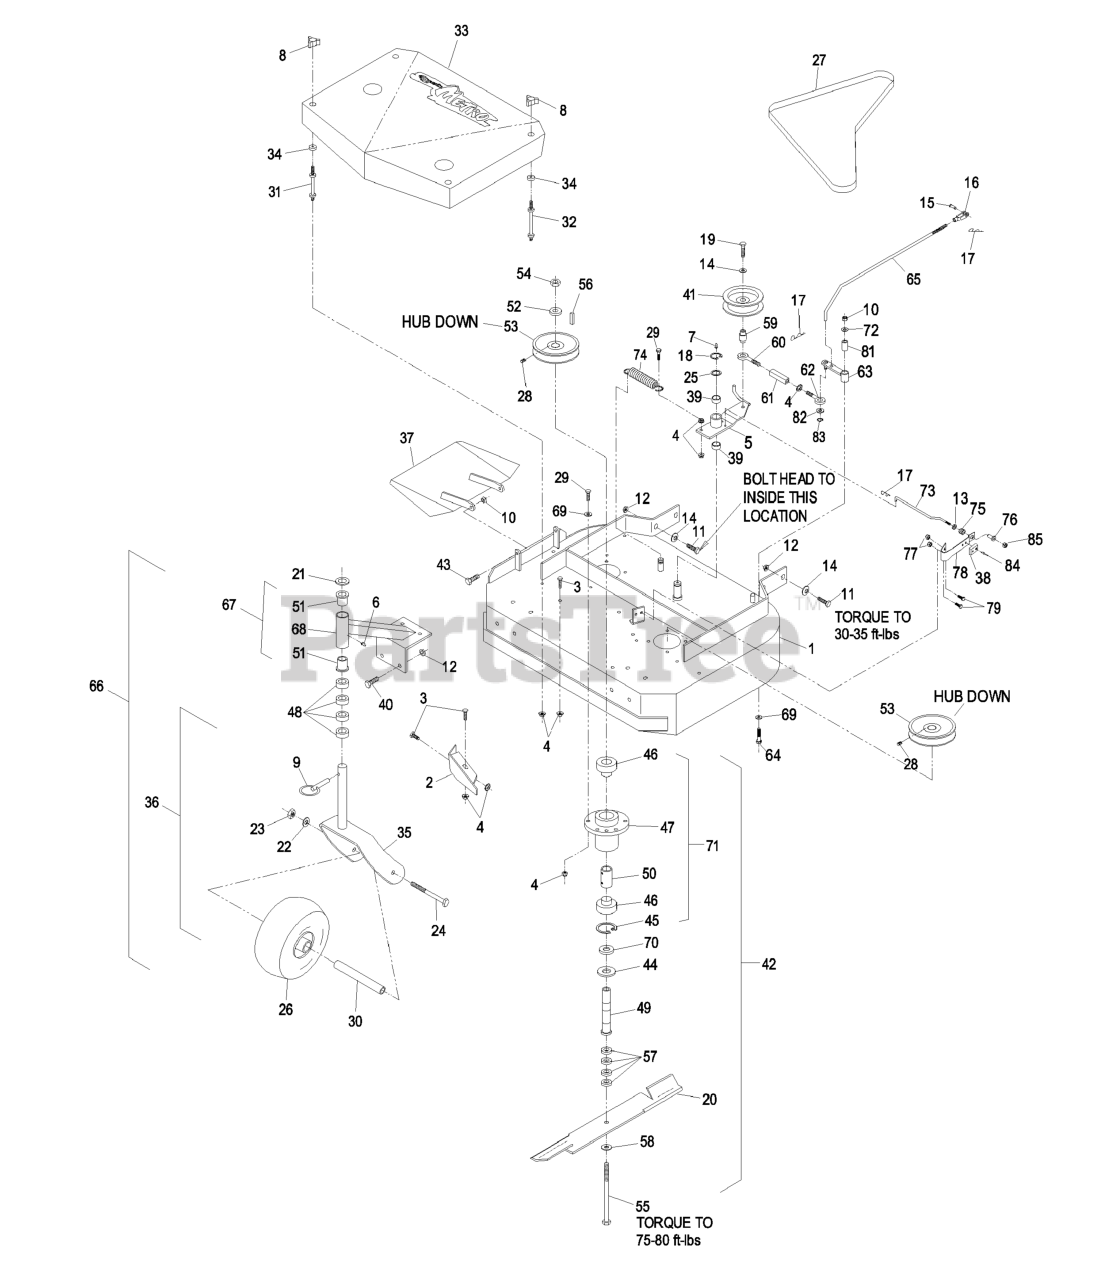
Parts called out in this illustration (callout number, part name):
2	BAFFLE-DOGLEG
8	KNOB-3 PRONG
13	RING-PUSH ON
15	PIN-CLEVIS
16	YOKE-ADJUSTABLE
17	PIN-COTTER
21	WASHER-FLAT
25	WASHER-SPINDLE
27	BELT,BLADE METRO 36
28	SCREW-SET
31	STUD-SHIELD, BELT (SHORT)
32	STUD-SHIELD, BELT (LONG)
37	WLD,CHUTE 36 RIGID
38	PAD-BRAKE
39	SLEEVE-BEARING
42	HOUSING,CUTTER COMPLETE(S
44	GUARD-BEARING, BOTTOM
46	BEARING
48	SPACER-CASTER
49	TUBE-SPINDLE, SHORT
50	SPACER-BEARING
51	BEARING-FLANGED
52	WASHER-RETAINER, SHEAVE
53	SHEAVE
55	SCREW-CAP, HH
58	WASHER-SPRING
59	BUSHING-ENGAGEMENT
60	EYEBOLT-THREAD, LH
61	BODY-TURNBUCKLE
62	EYEBOLT-THREAD, RH
63	ARM-ASSIST, 32/36
65	ARM-ASSIST, LINKAGE
66	CASTER/MOUNT ASM
67	SUPPORT ASM
69	WASHER-SPRING
70	SPACER-PULLEY/BEARING
73	ROD-BRAKE
74	SPRING-EXTENSION
75	SPRING-COMPRESSION
76	SPACER-FLANGED
78	PAD AND SPRING ASM
81	TUBE-PIVOT
